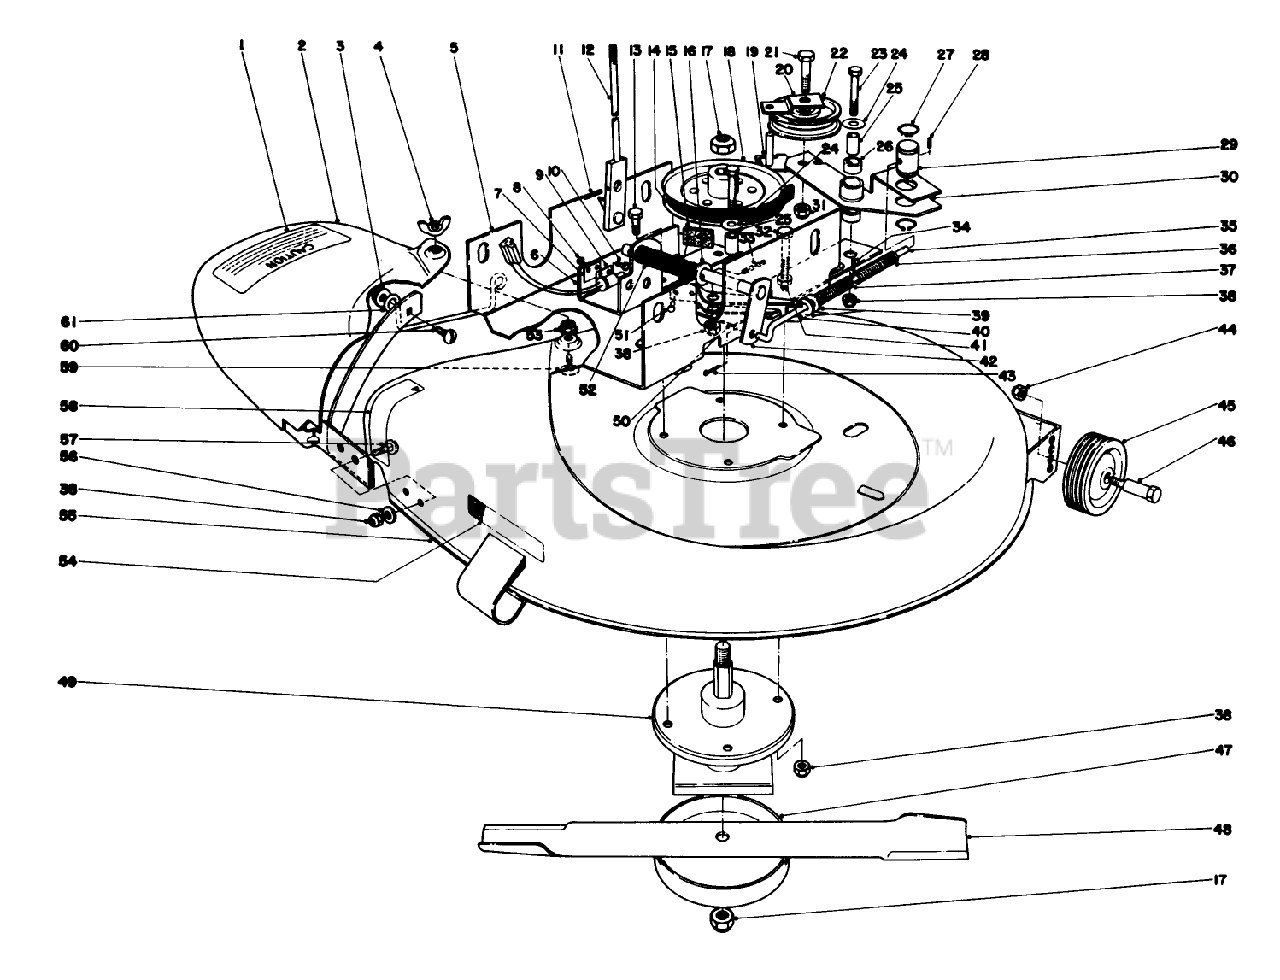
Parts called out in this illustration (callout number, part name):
3	NUT-LOCK, HHF
5	CHANNEL HT ADJ *R
8	NUT-KEPS
11	PIN-SPIRAL
13	SCREW-HH
14	V-BELT
16	WASHER-FLAT
17	NUT-SPECIAL
20	Belt Retainer Upper
21	SCREW-HH
23	SCREW-HH
24	WASHER-PLAIN
25	PIVOT SPACER
26	Bushing
27	RING-RETAINING
28	PIN-ROLL
31	NUT-LOCK, SIDE
32	SCREW-HH
33	PIN-SPRING
34	PIN-SPRING
38	NUT-LOCK, CONE
41	NUT-JAM
43	PIN-COTTER
56	WASHER-FLAT
57	BOLT-CARR
